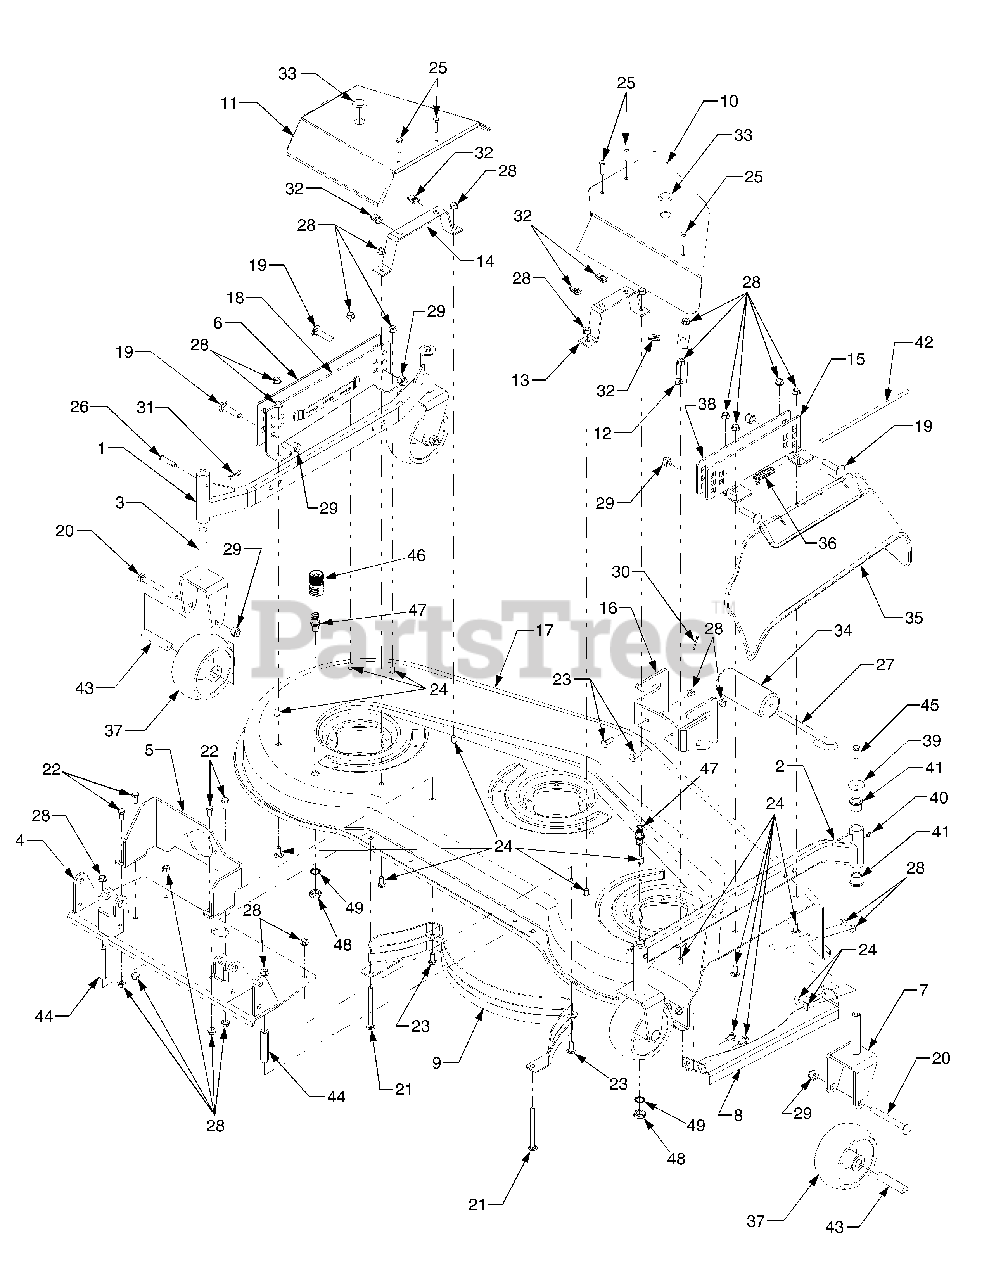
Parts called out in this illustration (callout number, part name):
1	Axle, Caster, LH
2	Axle, Caster, RH
3	Wheel Yoke, Rear
4	Bracket, Mounting
5	Bracket, Gear Box
6	Bracket, Caster LH Outer
7	Wheel Yoke, Front
8	Guard, Finger
9	Baffle, Rear Inner
10	Cover, Belt (R.H.)
11	Cover, Belt (L.H.)
12	Bracket, Belt Cover Mtg.
13	Bracket, Belt Cover Mtg.
14	Bracket, Belt Cover Mtg. LH
15	Bracket, Caster RH Outer
16	Bracket, Front Roller
17	Deck
20	Screw, Carriage, 1/2-13 x 4.5 GR5..
21	Screw, Carriage, 3/8-16 x 4.25 GR5
22	Screw, Hx Cap Lck 3/8-16 x .88 GR5
23	Carriage, Bolt 3/8-16 x 1.0
24	Carriage, Bolt 3/8-16 x .75
25	Screw, Hex Cap, 5/16-18 x 1 GR5 .
26	Pin, Clevis, 3/8 x 1.75
27	Pin, Roller 1/2 x 7.31
28	Nut, Flange Lock 3/8-16
29	Nut, Hex Nylon Lock 1/2-13 GR8
30	Pin, Cotter 1/8 x 1.0
31	Pin, Internal Cotter
32	Nut, "U" 5/16-18
33	Plug, Button
34	Roller, Front
35	Deflector, Chute
36	Spring, Torsion
37	Caster, Wheel w/Bearings
40	Fitting, Lube
41	Bearing, Flange, .754 ID
42	Rod, Deflector Chute
43	Axle, Caster Wheel
44	Spacer, .505 x .75 x 3.31Lg.
45	Screw, Hex Cap, 5/16-18 x .75 GR5
46	Adapter, Water Nozzle
47	Nozzle, Deck Water
48	Nut, Hex, M16-1.5
49	Washer, Lock
